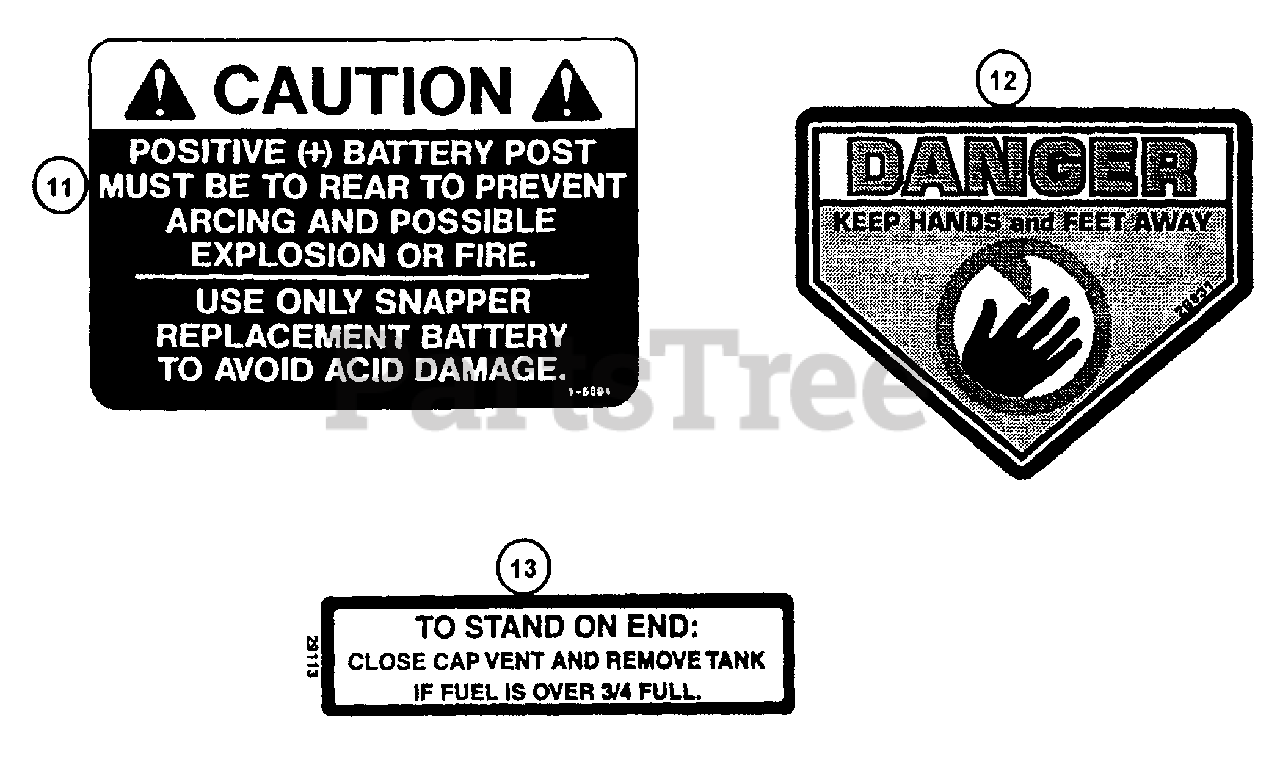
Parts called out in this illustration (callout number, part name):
11	DECAL, Battery Caution
12	DECAL, Danger (CPSC)
13	DECAL, Caution, Fuel (English)
